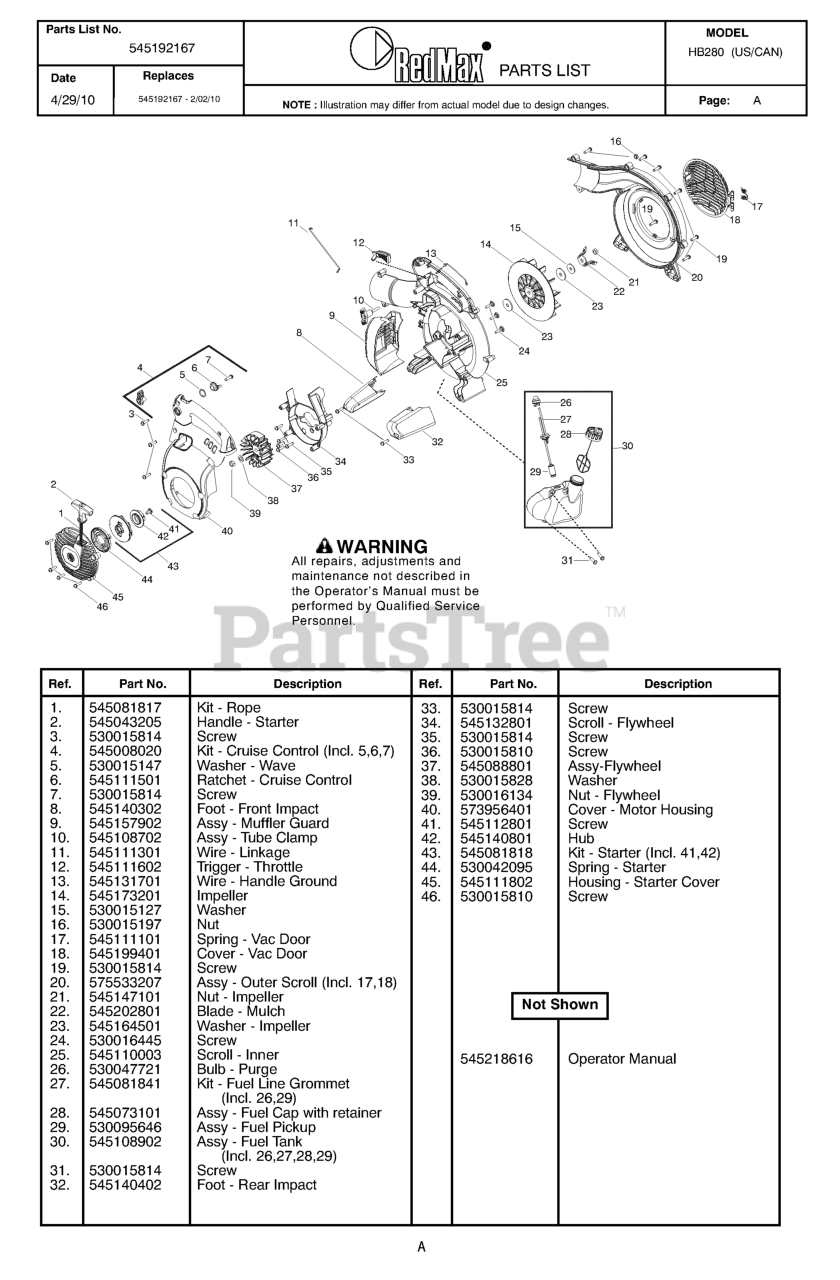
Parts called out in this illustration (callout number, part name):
1	KIT - ROPE
2	HANDLE - STARTER
4	KIT - CRUIS CONTROL (5,6,7)
5	WASHER - WAVE
6	RATCHET - CRUISE CONTROL
8	FOOT - FRONT IMPACT
9	ASSY - MUFFLER GUARD
10	ASSY - TUBE CLAMP
11	WIRE - LINKAGE
12	TRIGGER - THROTTLE
13	WIRE - HANDLE GROUND
14	IMPELLER
17	SPRING - VAC DOOR
18	COVER - VAC DOOR
20	OUTER SCROLL ASSY
21	NUT - IMPELLER
22	BLADE - MULCH
23	WASHER - IMPELLER
25	SCROLL - INNER
26	BULB - PRIMER
27	KIT - FUEL LINE GROMMET;26,29
28	ASSY - FUEL CAP W/RETAINER
29	ASSY - FUEL PICKUP
30	ASSY - FUEL TANK; 26,27,28,29
32	FOOT - REAR IMPACT
34	SCROLL - FLYWHEEL
36	SCREW
37	FLYWHEEL ASSY
39	NUT - FLYWHEEL
40	COVER, MOTOR HSG
43	KIT - STARTER (41,42)
44	SPRING - STARTER
45	HOUSING - STARTER COVER
46	SCREW
NI	OPERATOR
